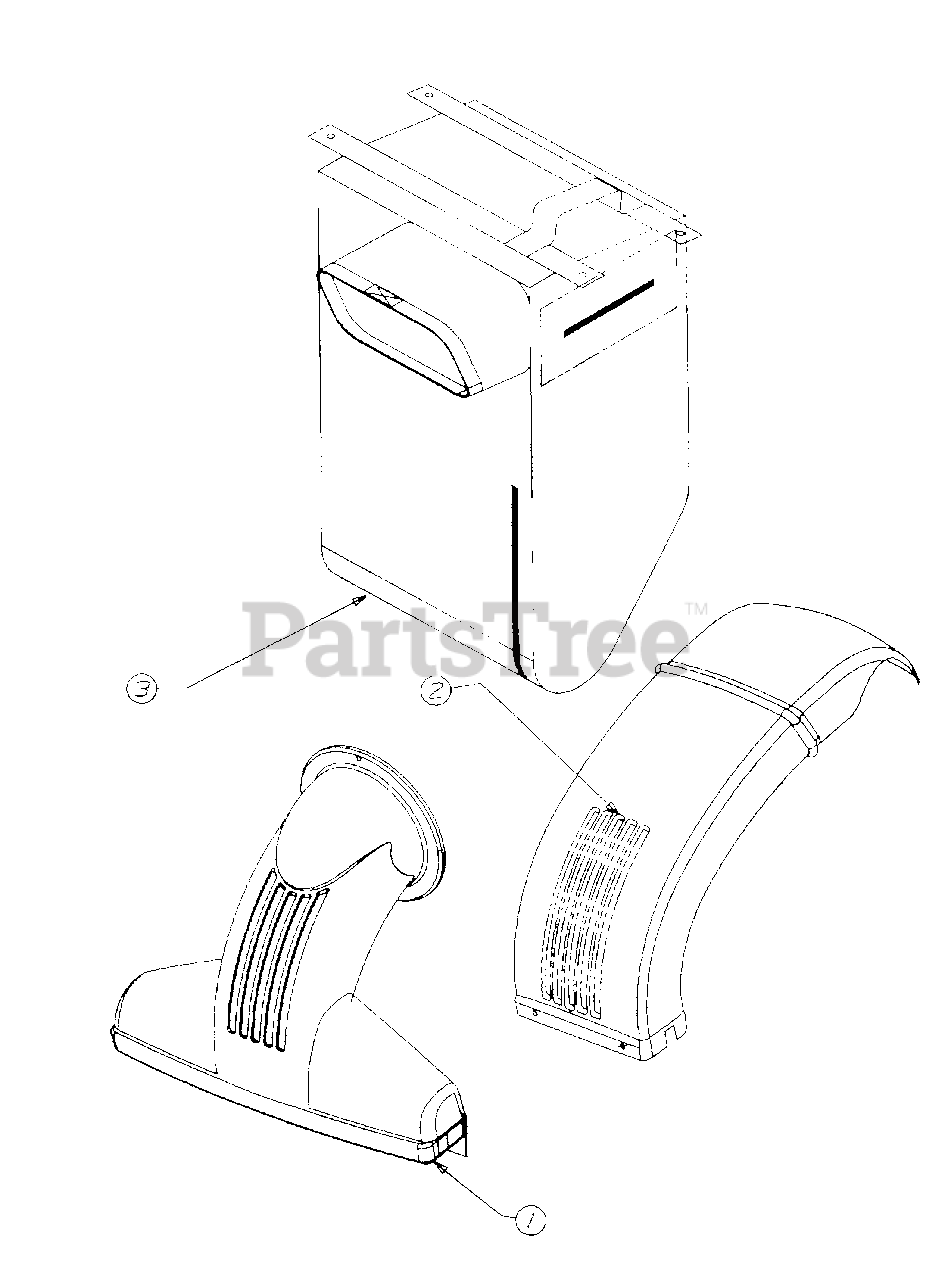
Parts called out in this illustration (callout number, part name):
1	NOZZLE ASS'Y. - VACUUM
2	CHUTE - DISCHARGE
3	BAG - VACUUM
